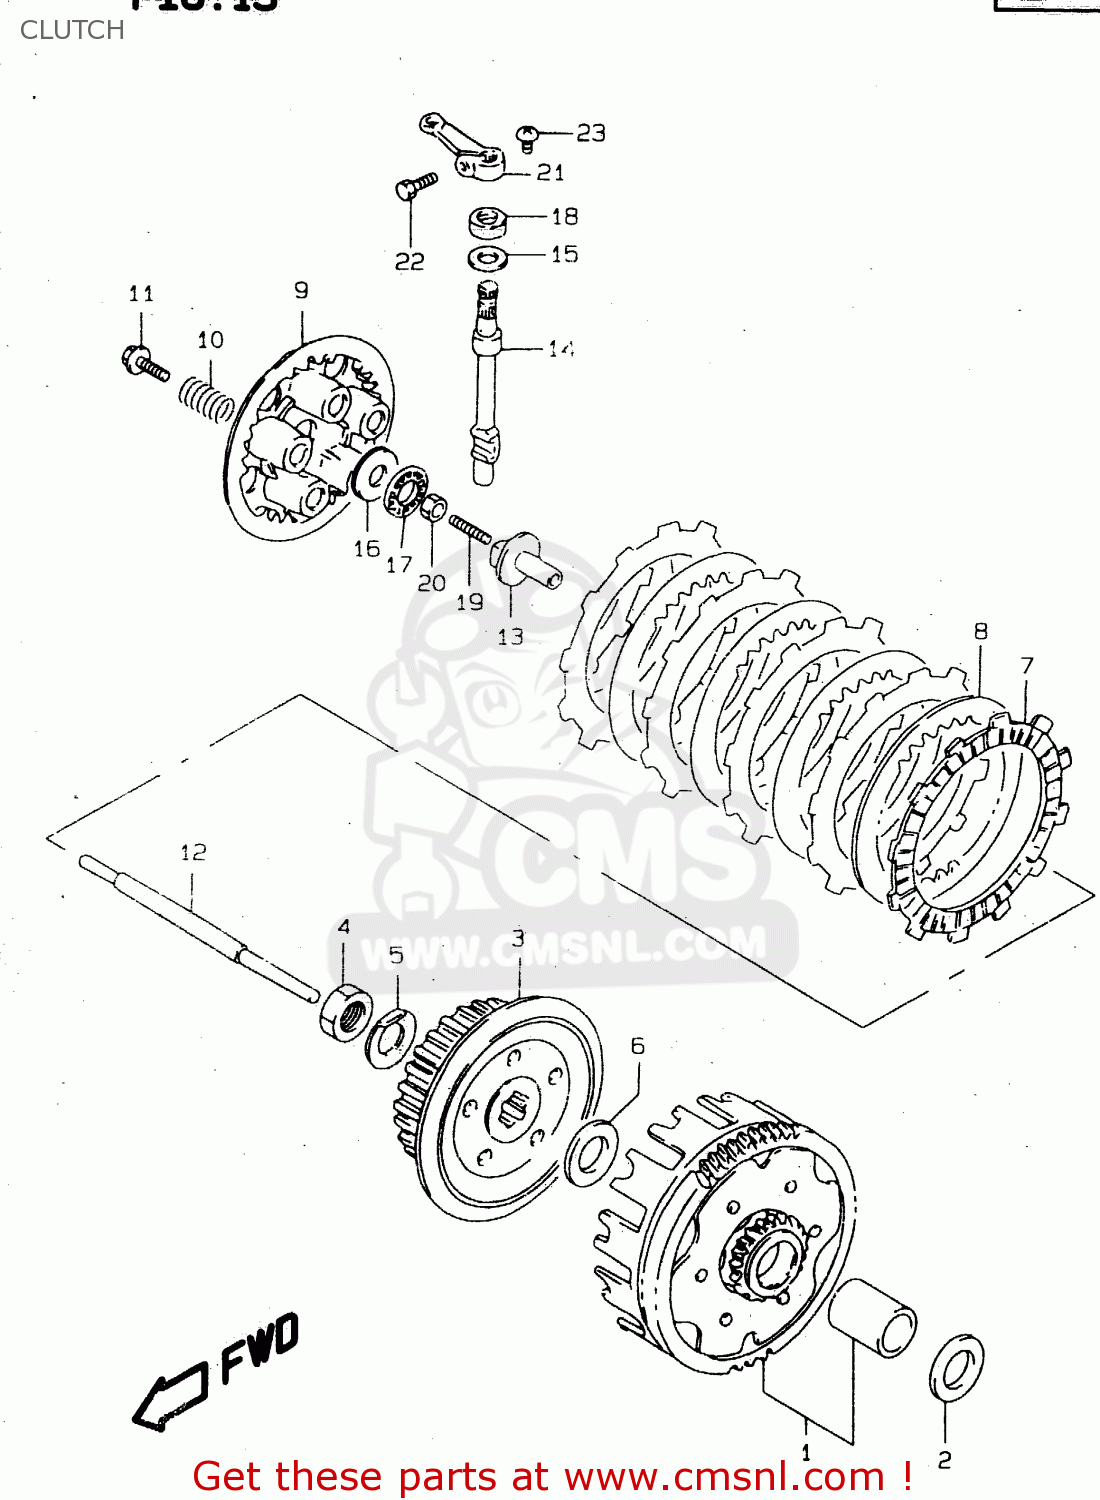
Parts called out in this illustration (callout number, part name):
1	GEAR ASSY,PRI DRIVEN(NT:59)
2	WASHER
3	HUB,CLUTCH SLEEVE
4	NUT
5	WASHER
6	WASHER
7	PLATE,CLUTCH DRIVE (NAS)
8	PLATE,CLUTCH DRIVEN (NAS)
9	PLATE,CLUTCH PRESSURE
10	SPRING
11	BOLT 5X16
12	ROD,CLUTCH PUSH
13	PIECE,CLUTCH PUSH
14	CAMSHAFT,CLUTCH RELEASE
15	WASHER,THRUST
16	WASHER(15.5X28X1)
17	BEARING(15X28X2)
18	SEAL,OIL(10X20X6)
19	SCREW(6X25)
20	NUT
21	ARM,CLUTCH RELEASE
22	BOLT
23	SCREW 6X10
